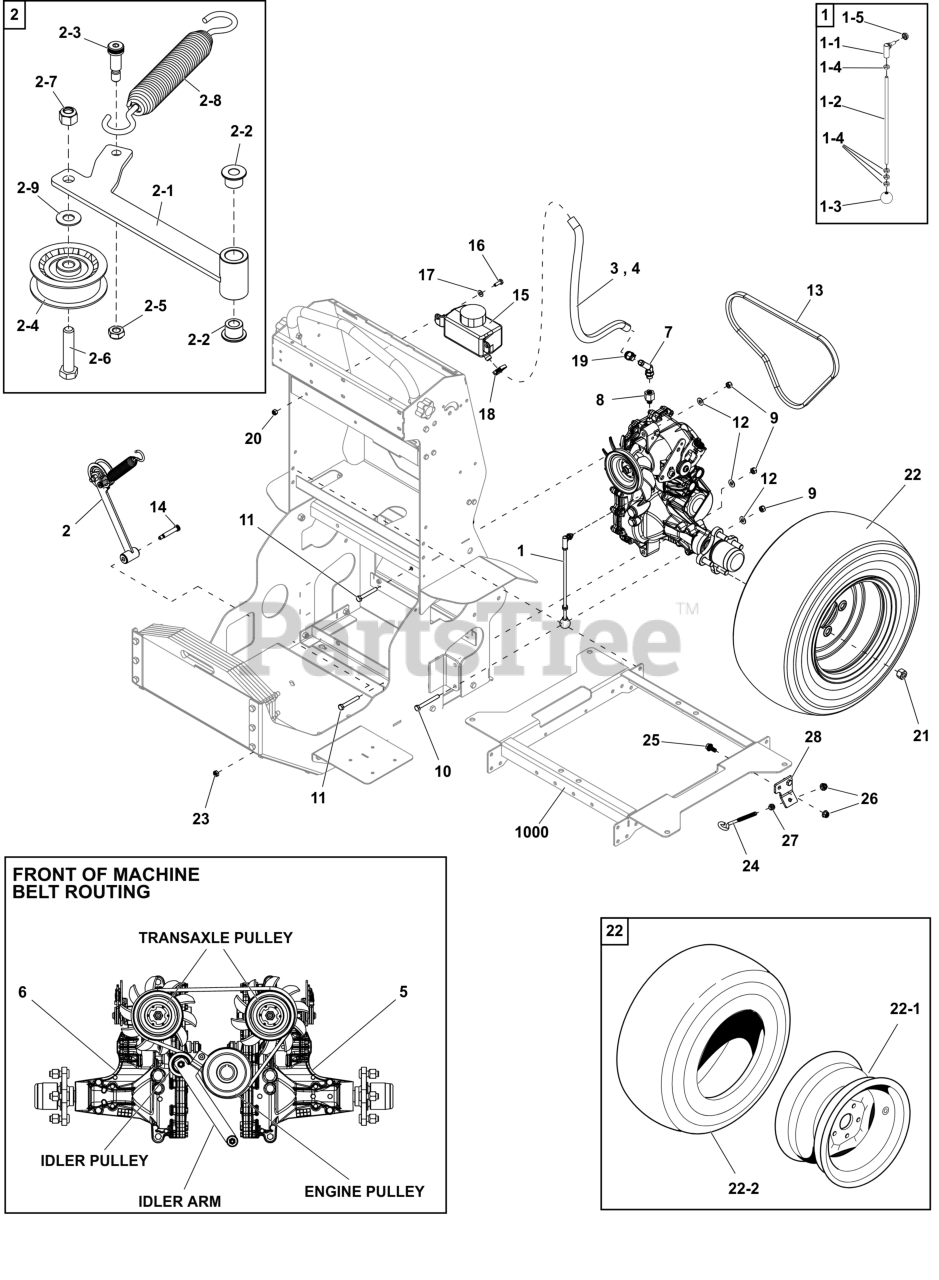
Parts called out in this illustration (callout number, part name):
1	ASM, TRANSMISSION RELEASE
1-1	ROD END, FEM 1/4-28 RH SS PTFE RACE STUD
1-2	ROD, CONTROL 1/4-28 THD X 9.00" MZ
1-3	KNOB, BALL 1.000 OD W/1/4-28 INSERT
1-4	NUT-HEX, JAM .250"-28 SS188
1-5	NUT-HEX-FGLK.250"-28 SS188
2	ASM, IDLER ARM
2-1	IDLER ARM W/ BUSHINGS
2-2	BUSHING, FLANGE 3/8 ID X 5/8 OD X 1/2 LG
2-3	BLT-SLDR, SH .375" X 0.750", .3125"-18 X.500" G8ZY
2-4	PULLEY IDLER 2.75" OD X 3/8" BORE
2-5	NUT-HEX-NYLK, .260"-20 TH SS188
2-6	SCR-CAP, HEX .375"-16 X 1.7500" SS188
2-7	NUT-HEX-NYLK, .375"-16 SS188
2-8	SPRING, Extension
2-9	WSHR-STL, FLT .406" X .875" X .050" IS SS188
3	HOSE, L EXP TANK, 18.5" LONG
4	HOSE, R EXP TANK, 18" LONG
5	TRANSAXLE, ZT3100, LH, ZL-GMPP-SB7B-1PXX
6	TRANSAXLE, ZT3100, RH, ZL-KMPP-SB7C-1PXX
7	FITTING, 08HB - 06MORB STRAIGHT
8	FITTING, 6410-04-06
9	NUT-HEX-NYLK, 0.3125"-18 SS188
10	SCR-CAP, HEX .3125"-18 X 2.750" SS188
11	SCR-CAP, HEX .3125"-18 X 2.250" SS188
12	WSHR-STL, FLT .343" X .750" X .050" SPC SS188
13	BELT, Transmission
14	BLT-SLDR SH.375"X1.75".3125"-18 X.50" SS188
15	HYDRO RES. # 71328, 350 ml
16	SCR-CAP, HEX .250"-20 X .750" SS188
17	WSHR-STL, FLT .281" X .625" X .050" IS SS188
18	CLAMP, PINCH 19.8mm TO 22.6mm
19	CLAMP, MINIATURE WORM GEAR MAH6
20	NUT-HEX-NYLK, .250"-20 SS188
21	NUT-LUG, .500"-20 ZP
22	ASM, WHEEL & TIRE 20" X 10.00" - 12 LAWN BOSS
22-1	RIM, Wheel
22-2	TIRE, (ONLY)
23	NUT-HEX-NYLK, .260"-20 TH SS188
24	EYE BOLT, 5/16 x 6-1/4 SST, 3" THRD LGTH
25	SCR-CAP, HSWH .313"-18 X .750" SS188
26	NUT-HEX-NYLK, FLG .3125"-18 SS188
27	NUT-HEX, .3125"-18 SS188
28	WELD, SPRING ANCHOR PLATE, VENTURE
